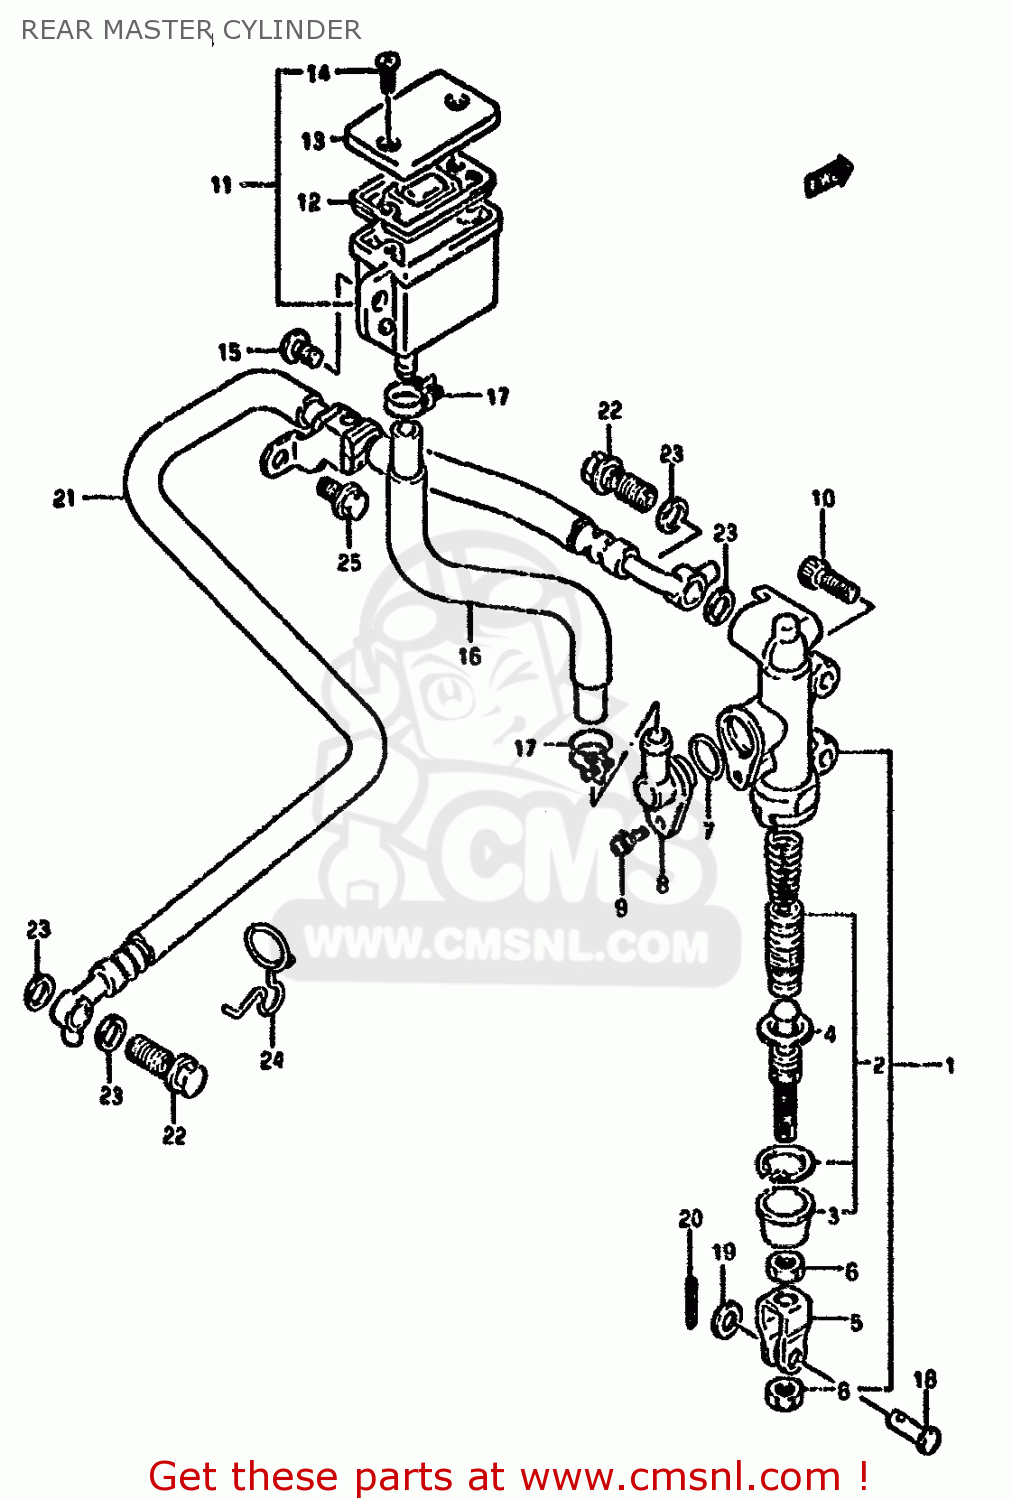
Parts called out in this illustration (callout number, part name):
1	CYLINDER ASSEMBLY,REAR MASTER
2	PISTON/CUP SET
3	BOOT
4	ROD,PUSH
5	YOKE
6	NUT
7	O RING
8	CONNECTOR
9	SCREW
10	BOLT
11	TANK ASSY,RESERVOIR
12	DIAPHRAGM
13	CAP
14	SCREW
15	SCREW 6X12
16	HOSE,RESERVOIR TANK
17	CLAMP
18	PIN
19	WASHER
20	PIN
21	HOSE,REAR BRAKE
22	BOLT UNION
23	WASHER(10X15X1.5)
24	GUIDE,BRAKE HOSE
25	BOLT
